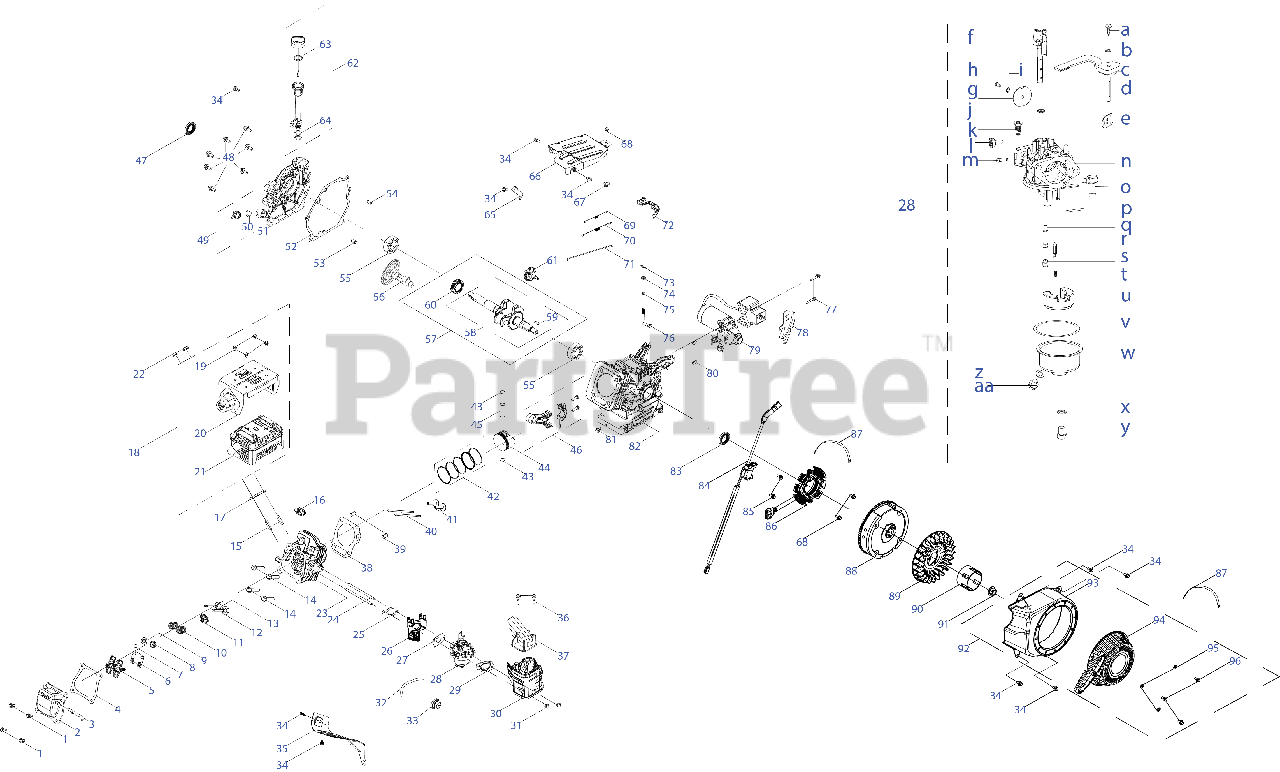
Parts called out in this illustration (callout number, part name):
1	BOLT M6 x 16
2	VALVE COVER
3	BREATHER HOSE
4	VALVE COVER GASKET
5	ROCKER ARM ASSEMBLY
6	ROCKER ARM BASE
7	EXHAUST VALVE ADJUSTER
8	INTAKE VALVE SPRING RETAINER
9	EXHAUST VALVE SPRING RETAINER
10	VALVE SPRING
11	INTAKE VALVE SEAL
12	INTAKE VALVE
13	EXHAUST VALVE
14	BOLT M8-1.25 x 55 GR10.9
15	STUD M8 x 36
16	SPARK PLUG
17	MUFFLER GASKET
18	MUFFLER ASSEMBLY
19	BOLT M5-.8 x 8 CL10.9
20	OUTER MUFFLER SHIELD
21	MUFFLER ASSEMBLY
23	CYLINDER HEAR ASSEMBLY 179/208
24	STUD M6-1 x 110 GR8.8
25	CARBURETOR INSULATOR GASKET
26	CARBURETOR INSULATOR
27	CARBURETOR GASKET
28	CARBURETOR ASSEMBLY HY-170-JA
29	CARBURETOR GASKET PLATE
30	HEATER BOX HOUSING
32	FUEL HOSE 3.2X6.5X530
34	BOLT M6-1 x 12 GR8.8
35	AIR SHIELD
36	BOLT M4.2 x 16
37	INTAKE HEATER BOX
38	CYLINDER HEAD GASKET
40	PUSH ROD
42	PISTON RING SET
43	PISTON PIN SNAP RING
45	PISTON PIN
46	CONNECTING ROD ASSEMBLY
47	OIL SEAL
48	BOLT M8-1.25 x 32 GR5.8
50	O-RING 15.8 x 2.5
51	CRANKCASE COVER
52	CRANKCASE COVER GASKET
53	DOWEL PIN
54	DOWEL PIN
57	CRANKSHAFT ASSEMBLY
58	CRANKSHAFT
59	FLYWHEEL KEY
60	DRIVE TIMING GEAR
61	GOVERNOR GEAR/SHAFT ASSEMBLY
62	DIPSTICK ASSEMBLY
63	DIPSTICK O-RING
64	OIL FILL TUBE O-RING
65	GOVERNOR SPRING BRACKET
66	GOVERNOR SHIELD
68	BOLT-M6-1 x 28 GR8.8
69	GOVERNOR SPRING
70	THROTTLE RETURN SPRING
71	GOVERNOR ROD
72	GOVERNOR LEVER
73	COTTER PIN
74	GOVERNOR SEAL
76	GOVERNOR SHAFT
77	BOLT M6-1 x 32 GR8.8
78	LOWER SHIELD
79	ELECTRIC STARTER
80	DOWEL PIN
81	OIL PLUG 1/8 NPT
83	OIL SEAL
84	IGNITION COIL ASSEMBLY
85	BOLT M6-1 x 25 GR8.8
86	CHARGING COIL
87	CABLE TIE - 3 x 150
89	COOLING FAN
90	STARTER CUP
91	FLYWHEEL NUT
92	RECOIL HOUSING ASSEMBLY
93	BLOWER HOUSING
94	RECOIL STARTER HOUSING
95	RECOIL FLAT WASHER
96	BOLT M6 x 10
